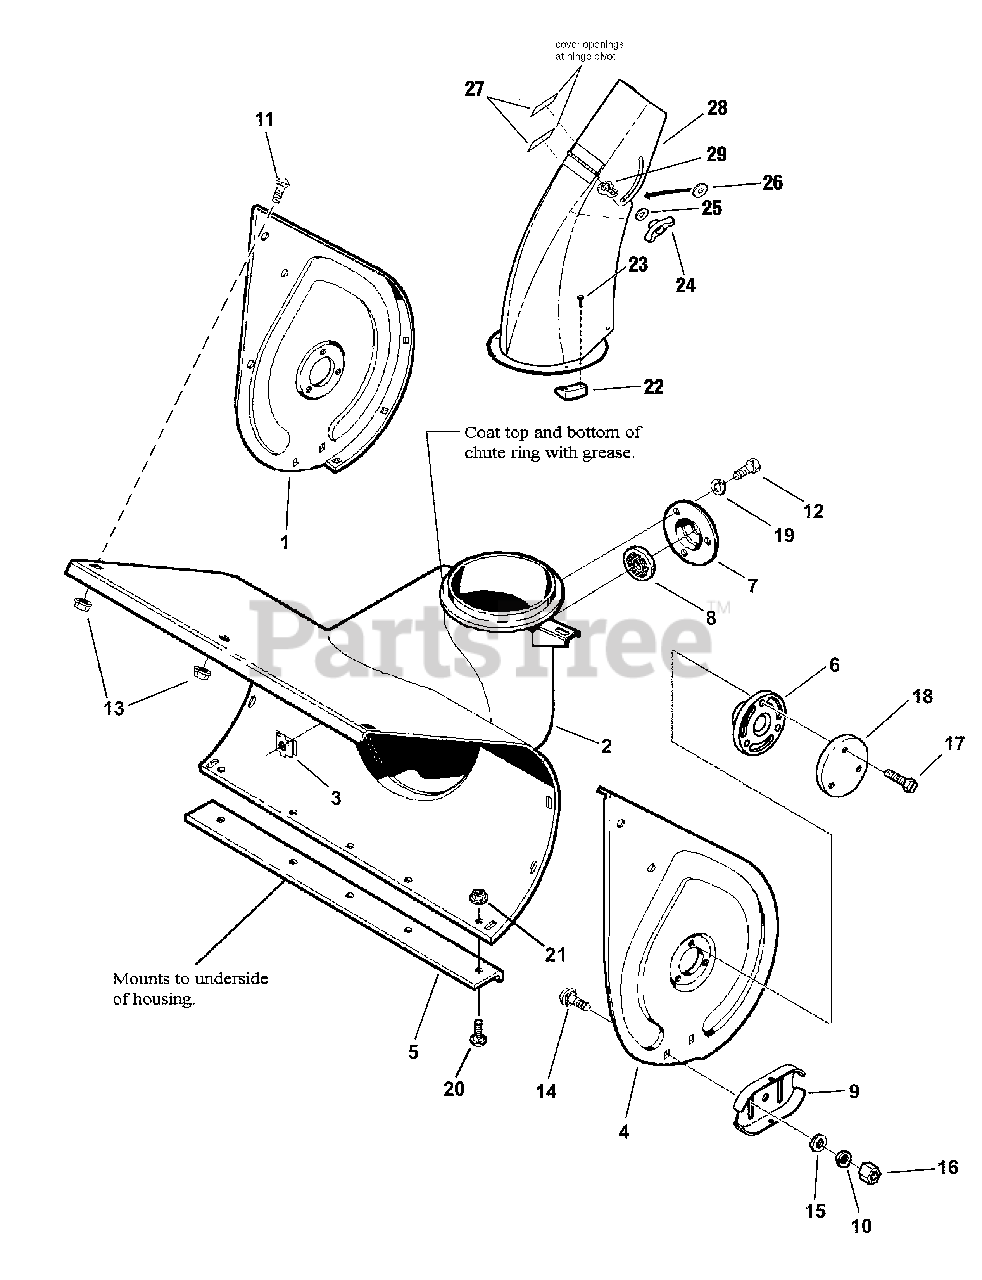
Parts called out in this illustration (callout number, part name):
1	END PLATE, RH- Auger Housing- Orange
2	WELDMENT, Auger Housing - 22" - Orange
2	WELDMENT, Auger Housing - 24" - Orange
3	RETAINER NUT, 5/16-18
4	END PLATE, LH- Auger Housing- Orange
5	BLADE, Scraper- 22"
5	BLADE, Scraper- 24"
6	BEARING, Auger
7	RETAINER, Bearing
8	BALL BEARING
9	SKID SHOE, Reversible- Orange
10	WASHER, 3/8" Split Lock
11	BOLT, 1/4-20 x 1/2" Short Square Neck Carriage, GR 5
12	SCREW, 5/16-18 x 5/8" Hex Head Cap, GR 5
13	NUT, 1/4-20 Hex Flange Lock Large
14	BOLT, 3/8-16 x 3/4" Square Neck Carriage
15	WASHER, 3/8" Flat
16	NUT, 3/8-16 Hex Nyloc
17	SCREW, 5/16-18 x 1" Hex Washer Self-Tap
18	CAP, Bearing, Orange
19	WASHER, 5/16" Split Lock
20	BOLT, 1/4-20 x 7/16" Short Square Neck Carriage, GR 5
21	NUT, 1/4-20 Hex Flange Lock
22	RETAINER, Spout
23	SCREW, #10-24 x 5/8" Hex Washer Self-Tap
24	WING KNOB, 5/16-18
25	WASHER, .34 x .69 x .08 Flat
26	WASHER, 3/8" Flat (Nylon)
27	ASSY, Decal/Steel Discharge Chute
27	ASSEMBLY, Decal/Steel Discharge Chute
28	WELDMENT, Steel Chute
29	BOLT, 5/16-18 x 3/4" Square Neck Carriage, GR 5
